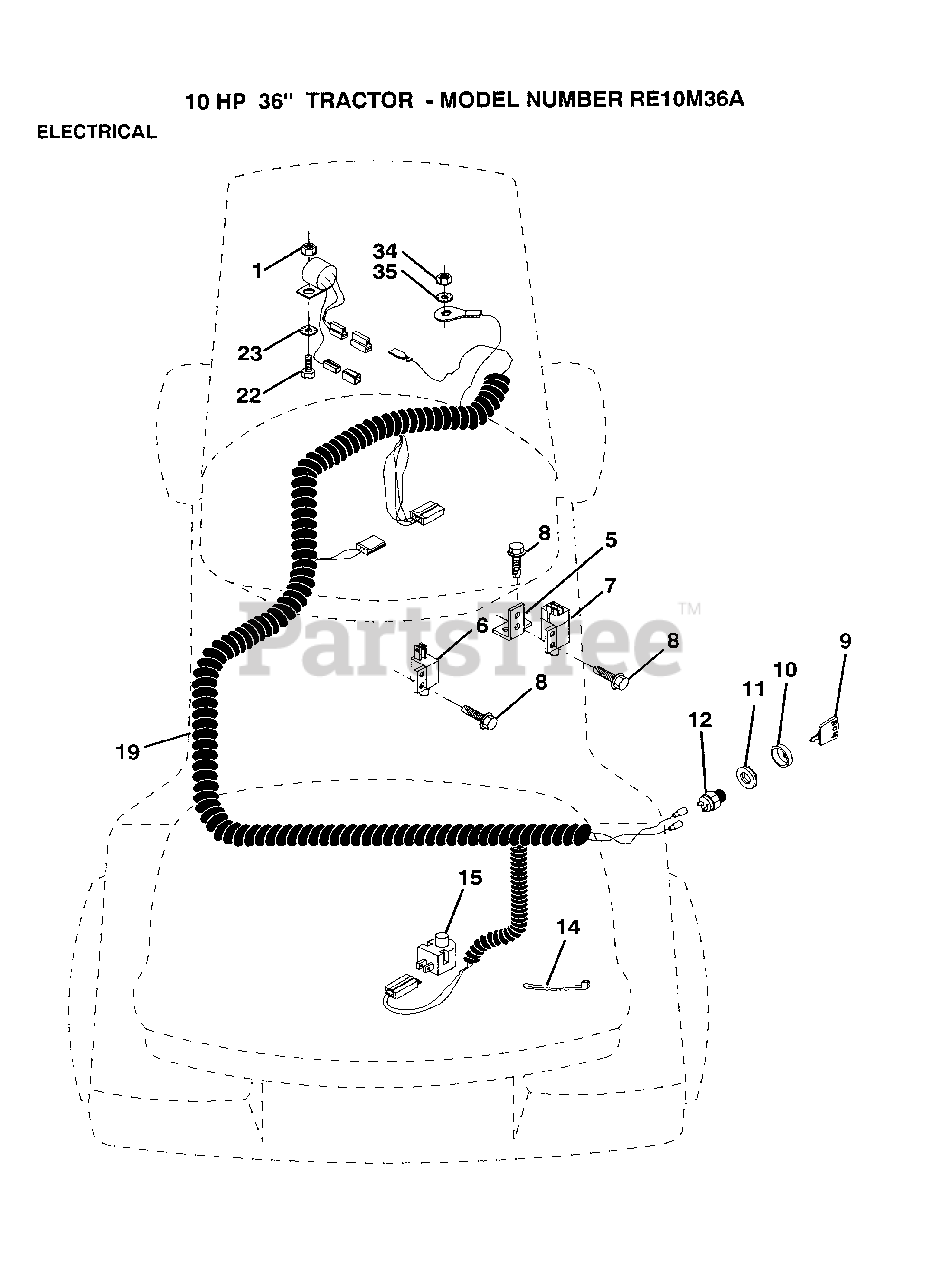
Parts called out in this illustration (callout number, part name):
1	NUT
5	BRACKET LT
6	SWITCH-INTER. GT
7	SWITCH INTERLOCKT
8	SCREW
11	NUT IGNITION
12	"SWITCH,IGNITION"
14	WIRE TIE
15	SWITCH SEAT
19	"HARNESS,IGNITION"
22	BOLT
34	NUT
35	LOCKWASHER
